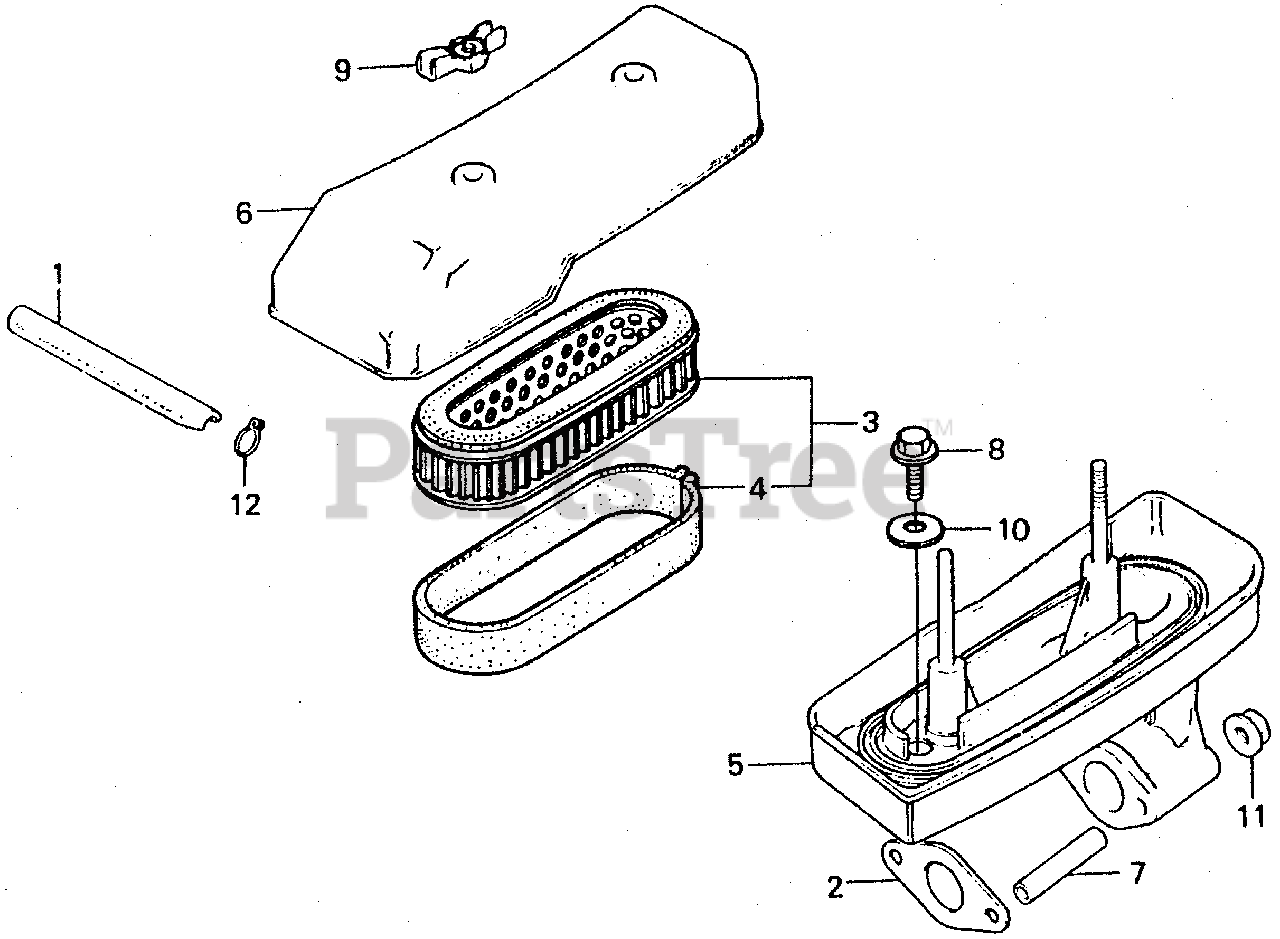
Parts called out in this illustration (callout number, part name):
1	TUBE, BREATHER
2	GASKET, AIR CLEANER
3	ELEMENT, AIR CLEANER
4	FILTER (OUTER)
5	HOUSING, AIR CLEANER
6	COVER, AIR CLEANER *NH1* (BLACK)
7	COLLAR, AIR CLEANER HOUSING
8	BOLT, FLANGE (6X12) (CT200)
9	WINGNUT, AIR CLEANER COVER
10	WASHER, HEADLIGHT CASE
11	NUT, FLANGE (6MM)
12	CLIP, TUBE (B12.5)
